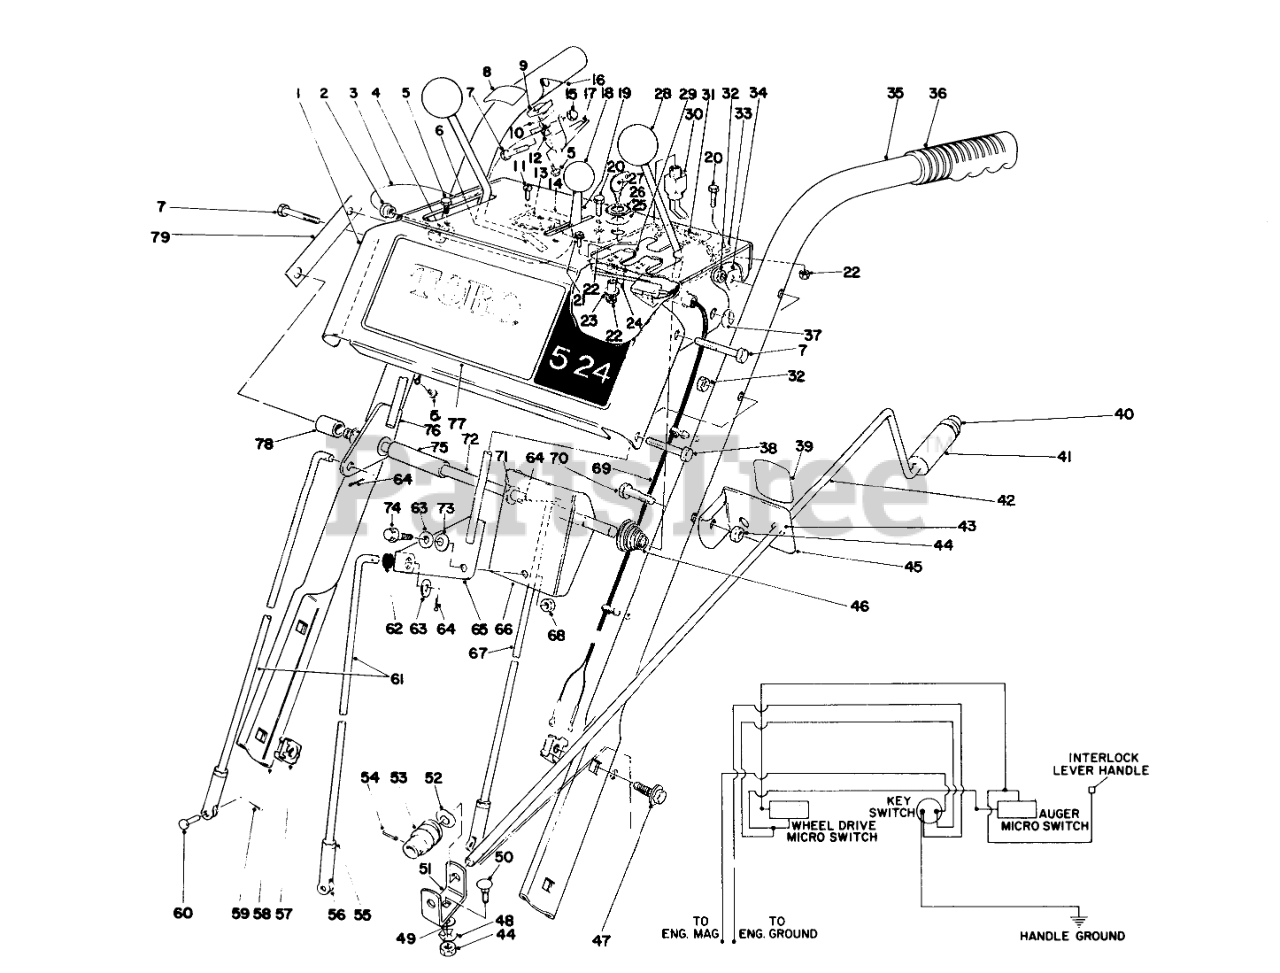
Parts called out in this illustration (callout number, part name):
1	ESCUTCHEON PLT B
2	Snap Bushing
3	Wire Assembly
4	PLASTIC CLIP
5	SCREW
6	NUT-SPEED
7	SCREW-HH
8	INTERLOCK DECAL
9	Insulator
10	INTERLOCK CONTACT
11	SCREW-SPH
12	WASHER INSULATOR
13	MICRO SWITCH
14	SWITCH MTG PAD
15	NUT-CAP
16	INTERLOCK SPRING
17	SAFETY INTRLOCK LEVER
18	CONTROL KNOB
19	THROTTLE CONTROL
20	HEX HEAD SEMS 10-24X1/2
21	SCREW-SRH
22	Nut
23	INTERLOCK SPACER
24	INTERLOCK SPRING
25	WASHER-TOOTH, INTERNAL
26	NUT-HH
27	Key
29	Slide Interlock
30	SWITCH-ON / OFF
31	INSTRUCTION DECAL
33	CABLE CLAMP
34	Washer
35	LEFT HANDLE
36	Grip Handle
37	RING-CLIP
38	SCREW-HH
39	CHUTE DECAL
40	RETAINER-PUSH ON
41	GRIP-CONTROL, CHUTE
42	CHUTE CONTROL ROD
43	Bushing
44	NUT-LOCK, NI
45	Chute Control Rod Mounting (Incl. Ref. #39 & 43)
46	CONICAL SPRING
47	SCREW-HHF
48	WASHER-LOCK
49	WASHER
50	BOLT-CARR
51	WORM BRACKET
52	WASHER-SPRING
53	GEAR-WORM, CHUTE
54	PIN-SPRING
55	NUT-HJ
56	CLEVIS
57	Retained Nut
58	RIGHT HANDLE
59	PIN-COTTER
60	PIN-CLEVIS
61	SPEED SELECTOR ROD
62	GROMMET-RUBBER
63	WASHER-FLAT
64	PIN-COTTER
65	SHIFT LEVER WA
66	SHIFT BRACKET
67	TRACTION CONTROL ROD
68	NUT-LOCK, CONE
69	Wire Harness Interlock
70	SCREW-HH
71	WASHER-FLAT
72	PIVOT ROD
73	7/16 SPRING WASHER
74	SHOULDER SCREW
75	SHIFT LEVER SPACER
76	LEVER WA
77	ESCUTCHEON DECAL
78	AUGER LEVER SPACER
79	ESCUTCHEON SUPT STRAP
